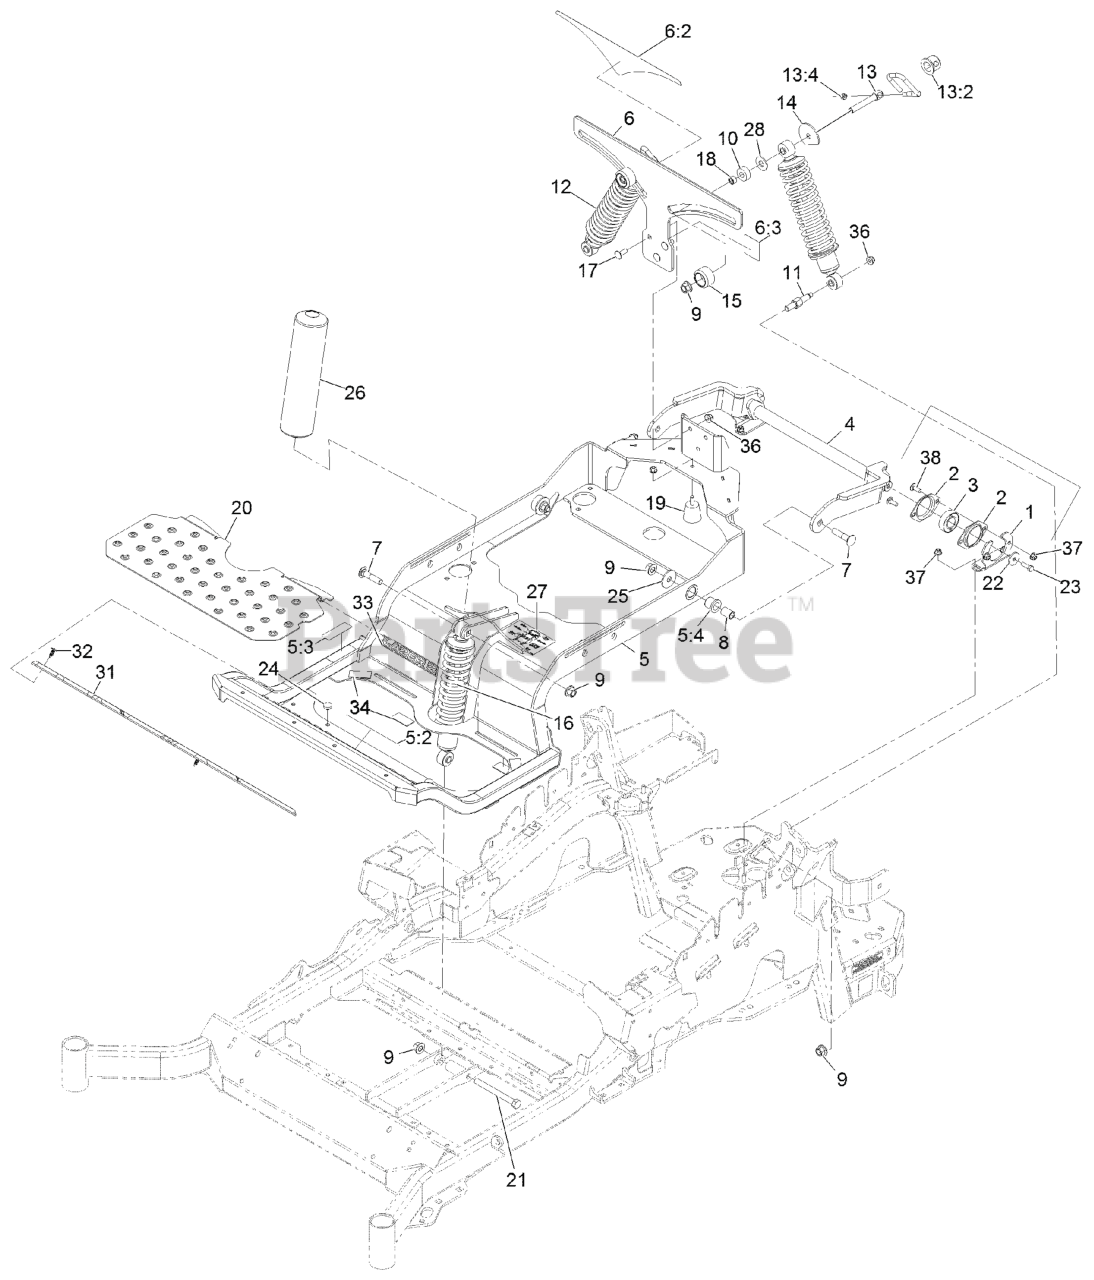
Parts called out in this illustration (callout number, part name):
1	BRACKET-BEARING
2	HOUSING-BEARING, FLANGE
3	BEARING
4	ARM-TRAILING
5	SUBFRAME ASM
5:2	DECAL-DANGER
5:3	DECAL-BRAKE, PARKING
5:4	BUSHING-FLANGE
6	BRACKET-MOUNTING
6:2	DECAL-ADJUSTMENT, RIDE
6:3	DECAL-LOCK, CAM
7	SCREW-CARR
8	SPACER-ALUMINUM
9	Nut-Lock 1/2-13
11	BOLT-SHOULDER
12	SHOCK/SPRING ASM
13	CAM LOCK ASM
13:2	CAP-LOCK
13:4	NUT-HEX
14	PLATE-STOP
15	KNOB-FRONT
16	SHOCK ASM-FRONT
16	SHOCK/SPRING ASM
17	SCREW-CARR
18	BEARING-NEEDLE
19	BUMPER-RUBBER
21	SCREW-HH
22	WASHER-FLAT
23	SCREW-HH, THREAD LOCKING
25	WASHER-THRUST
26	COVER-SHOCK
27	DECAL-SERVICE AID
28	WASHER-FLAT
31	FLOOR MAT
32	PLUG-PLASTIC
33	DECAL-LAZER LOGO
34	PAD-RUBBER
36	NUT-HF, NI
37	NUT-HF, NI
38	BOLT-CARR
